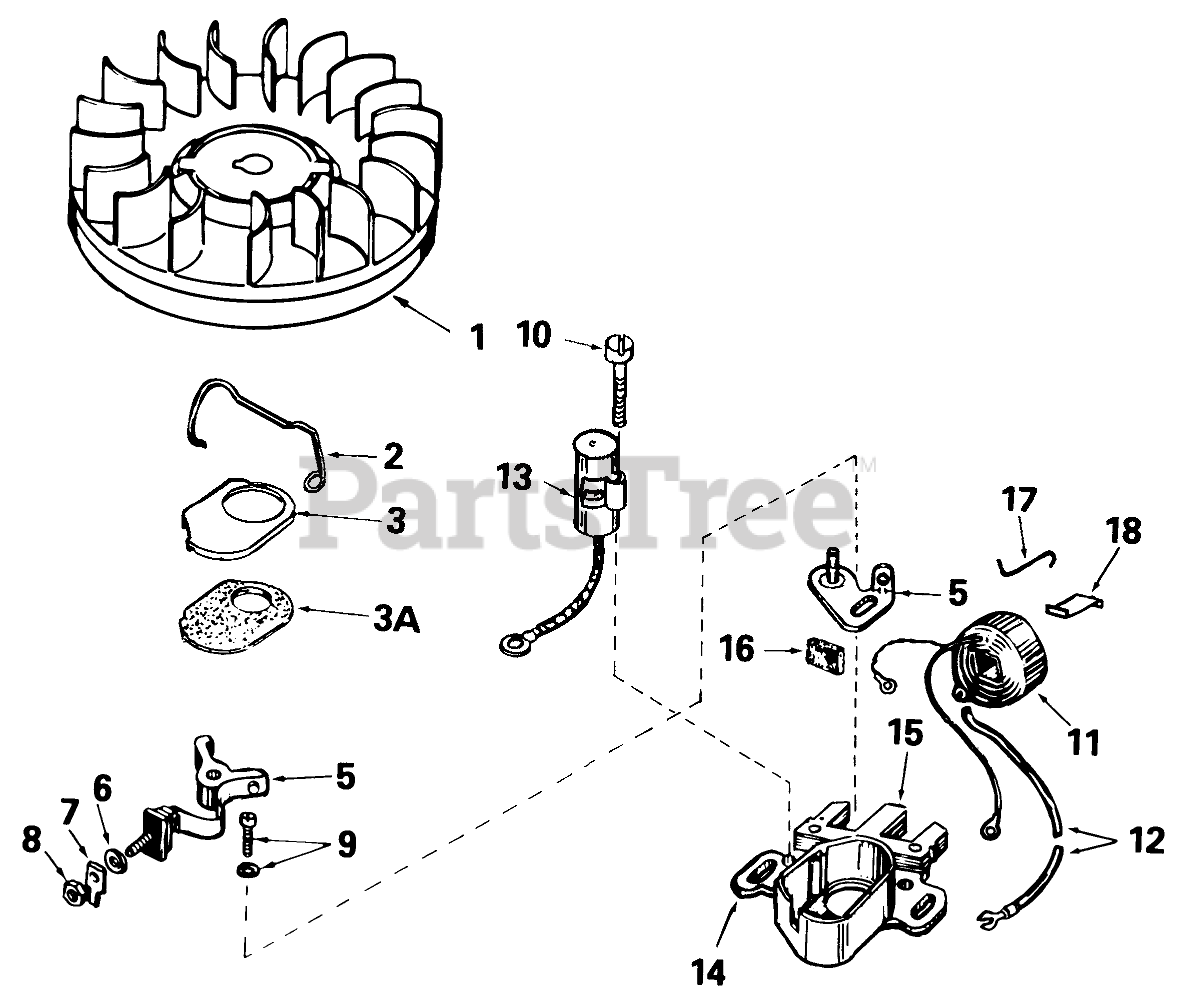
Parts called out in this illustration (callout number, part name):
1	Flywheel
2	Spring Breaker Box
3	Cover-Dust
3A	Gasket, Dust Cover
5	Breaker Assy.
6	Washer
7	Terminal, Ground
8	DECAL
9	Breaker Screw
10	Condenser Screw
11	Coil Assy. (Incl. Ref. #12)
12	Wire, Lead
13	Condenser
14	Core & Plate
15	Stator Assy. (Incl. Ref. #2 thru 14, 16 & 17)
16	Felt,Cam Wiper
17	Clip, Coil
